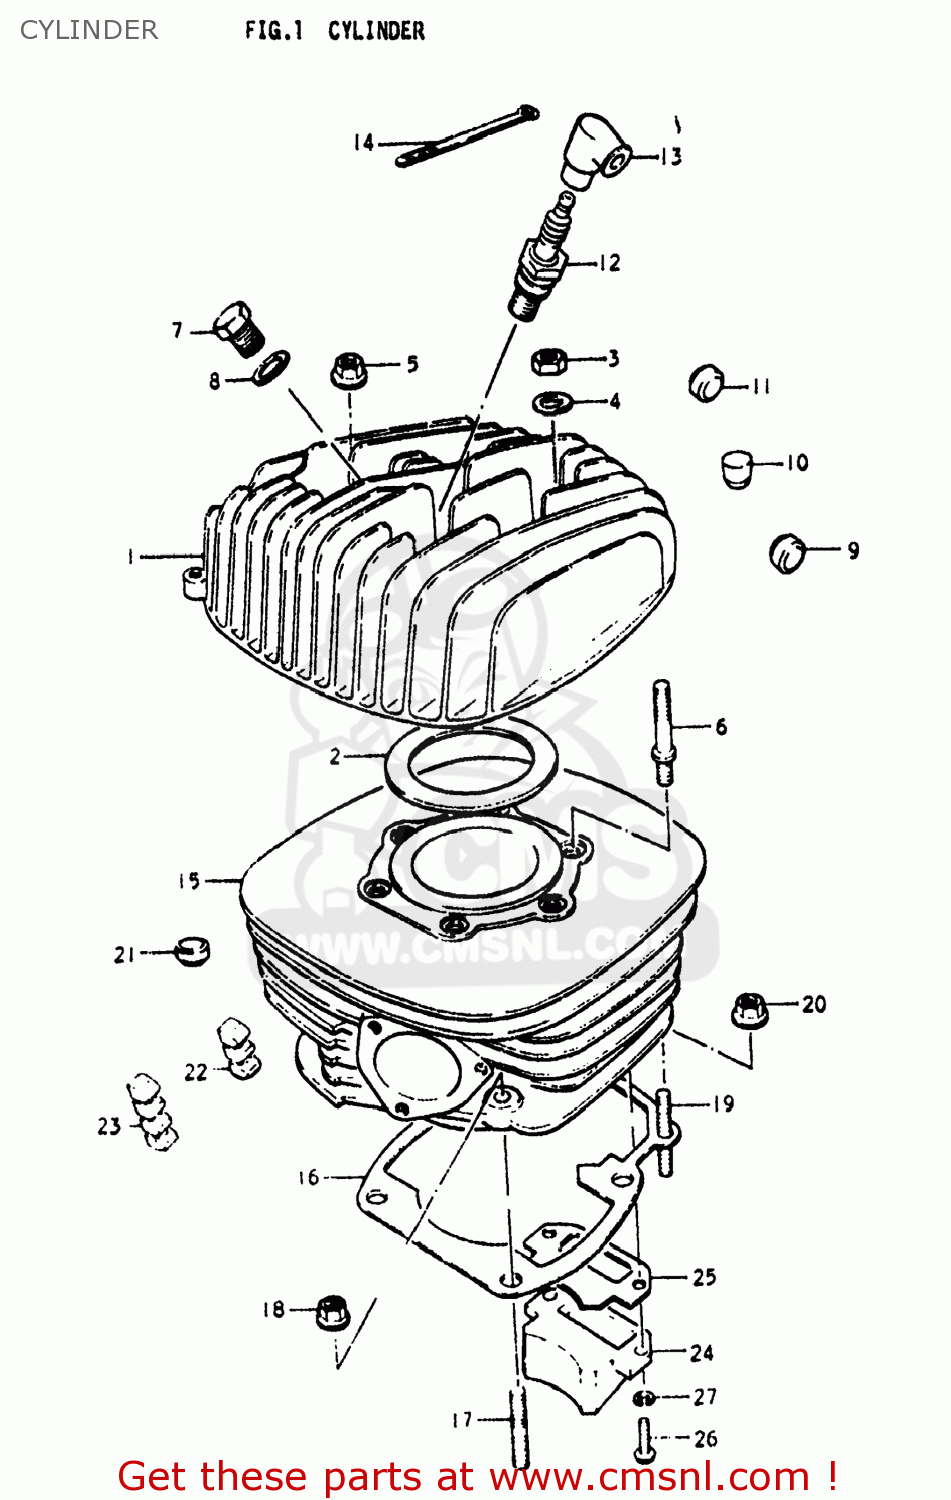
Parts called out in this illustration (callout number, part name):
1	HEAD,CYLINDER
2	GASKET,CYLINDER HEAD (NAS)
3	NUT (8MM)
4	WASHER
5	NUT
6	BOLT,STUD
7	PLUG
8	GASKET(14X19.2X2) (NAS)
9	PAD,CYLINDER
10	PAD,CYLINDER HEAD
11	PAD,CYLINDER HEAD
12	SPARK PLUG
13	CAP,SPARK PLUG
14	CLAMP
15	CYLINDER
16	GASKET,CYLINDER (MCA)
17	STUD 10X25
18	NUT
19	STUD 8X25
20	NUT
21	PAD,CYLINDER HEAD
22	PAD,CYLINDER
23	PAD,CYLINDER
24	VALVE ASSY,REED
25	GASKET,REED VALVE (MCA)
26	SCREW
27	LOCK WASHER
